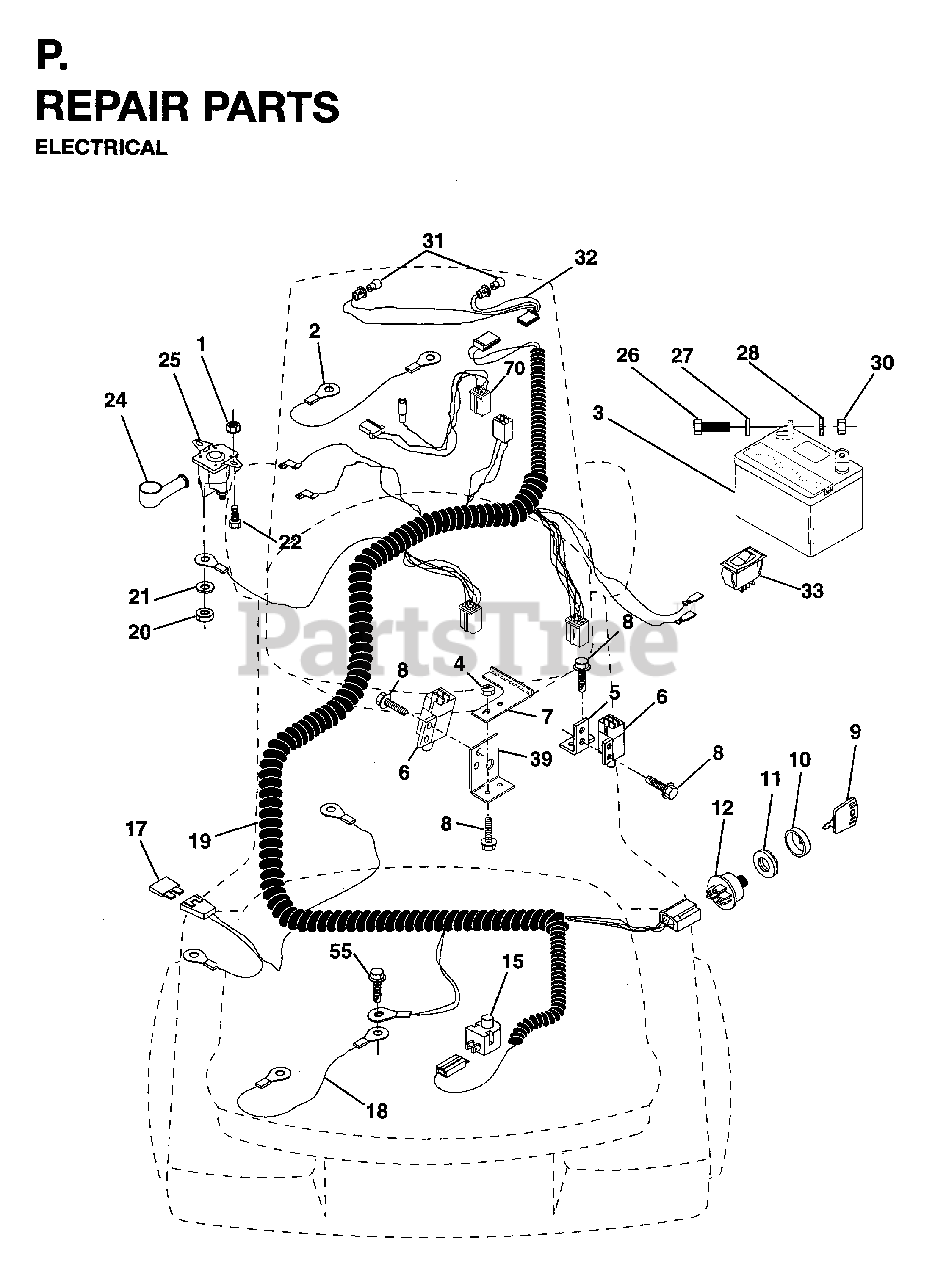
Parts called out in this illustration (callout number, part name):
1	NUT.CROWNLOCK.1/4
2	CABLE ASM
3	BATTERY
5	BRACKET LT
6	SWITCH INTERLOCKT
7	KEEPER, ACTUAT. L.R.
9	KEY MLD GEN DELTA
10	COVER SWITCH KEY
11	KIT-WASHER/NUT
12	SWITCH KIT, IGN.
15	SWITCH SEAT
19	HARNESS IGN LR NLA
20	NUT
21	LOCKWASHER
22	BOLT
24	TERMINAL COVER
25	KIT SOLENOID .95
28	LOCKWASHER
30	NUT
31	LIGHTBULB
32	HARNESS LIGHT SOCKET
33	SWITCH LT
70	HARNESS, ENGINE
